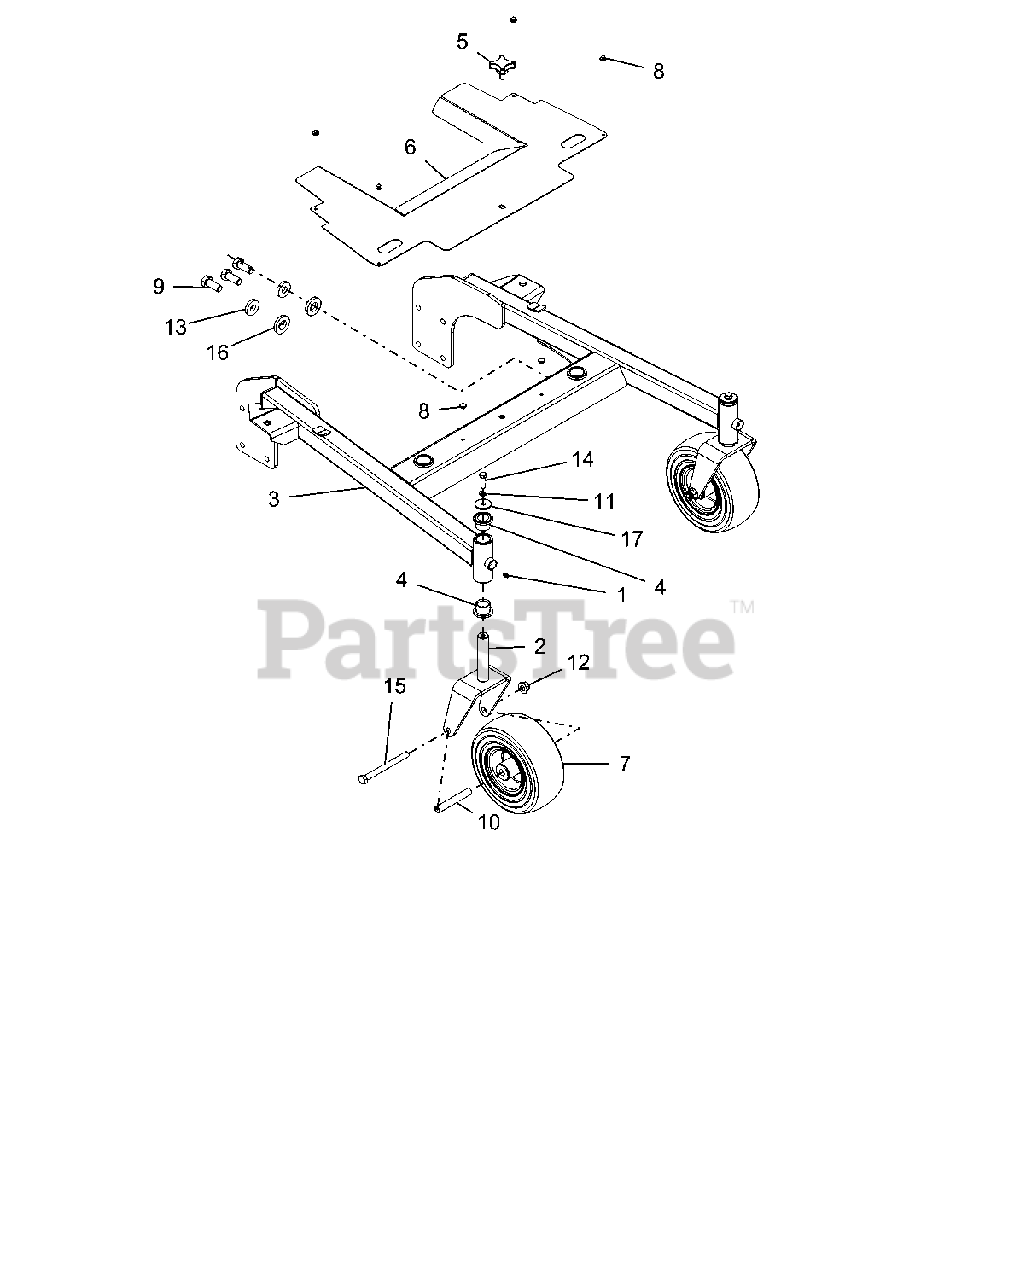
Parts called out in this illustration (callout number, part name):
1	FTG, 1/4-28 STRGT GREASE ZERK
2	WLDMT, FRONT WHEEL FLOAT WALK
3	WLDMT, DECK FRAME 48 FLWLK
4	BRG, FLANGE 1.00 X 1.25 X 1.00
5	KNOB, 3/8-16 x .75
6	SHIELD, BELT 48" HYDRO WALK
7	9X3.5-4 CAREFREE BLT TOGETHER
8	BUMPER GROMMET .125 X .25 REV
9	BLT-HEX .62-11X1.50 GR8 YWZC
10	TUBE, CASTER AXLE
11	WSHR-LK .38X.094 REG YWZC
12	NUT-LK-NYL-FLG .50-13 YWZC
13	WSHR-FL-STL .630X1.50X.25 YWZC
14	BLT-HEX .38-16X1.25 GR5 YWZC
15	BLT-HEX .50-13X5.50 GR5YWZC
16	WSHR-FL-STL .905X1.750X.25 YWZC
17	WSHR-FL-STL .380X1.50X.125 YWZC
